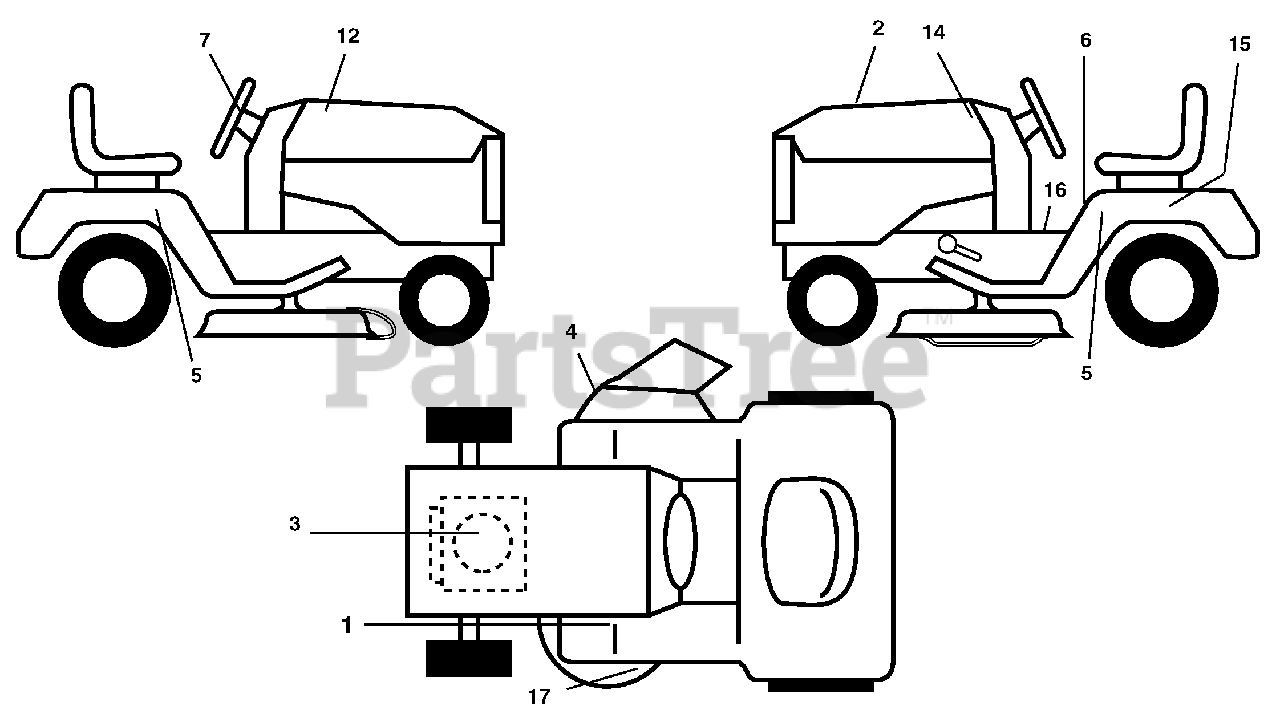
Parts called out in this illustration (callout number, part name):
1	Decal, Clutch/Brake Eng/Fr
2	Decal, Replacement
3	Decal, Engine HP
4	Decal Warning
5	Decal SDFNDR 5SP
6	Decal, Fender Danger English
7	Decal Ins Str Wh
12	Decal, Hood RH
14	Decal, Hood LH
15	Decal, Caution, Battery
16	Decal, Oper Sdl P/L Gear Dr Eng
17	Decal, V-Belt Sch.
17	Decal, Handle Lft Height Adj.
17	Manual, Operator's (E&F)
17	Manual, Parts (E&F)
